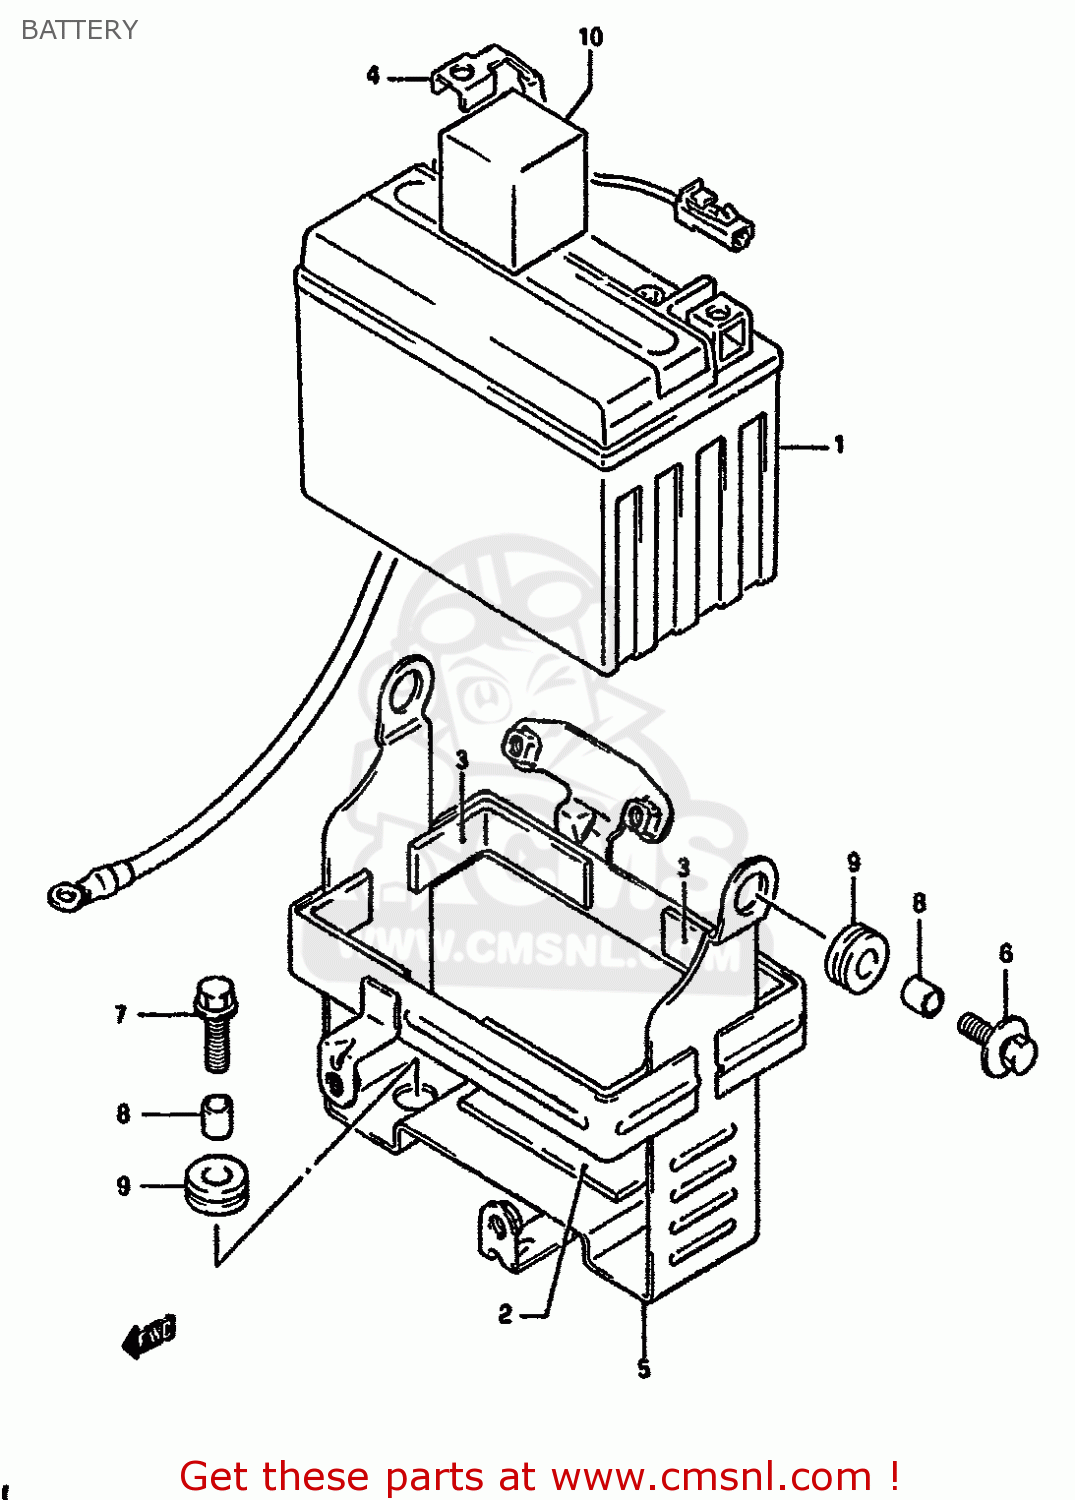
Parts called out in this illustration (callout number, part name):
1	BATTERY (YTX9-BS,12V8AH)
2	CUSHION,BATTERY(80X27X3)
3	PROTECTOR,20X9
4	WIRE,BATTERY MINUS LEAD
5	HOLDER,BATTERY
6	BOLT
7	BOLT 6X20
8	SPACER(6.2X9X7.5)
9	CUSHION
10	CUSHION,BATTERY 35X35X
